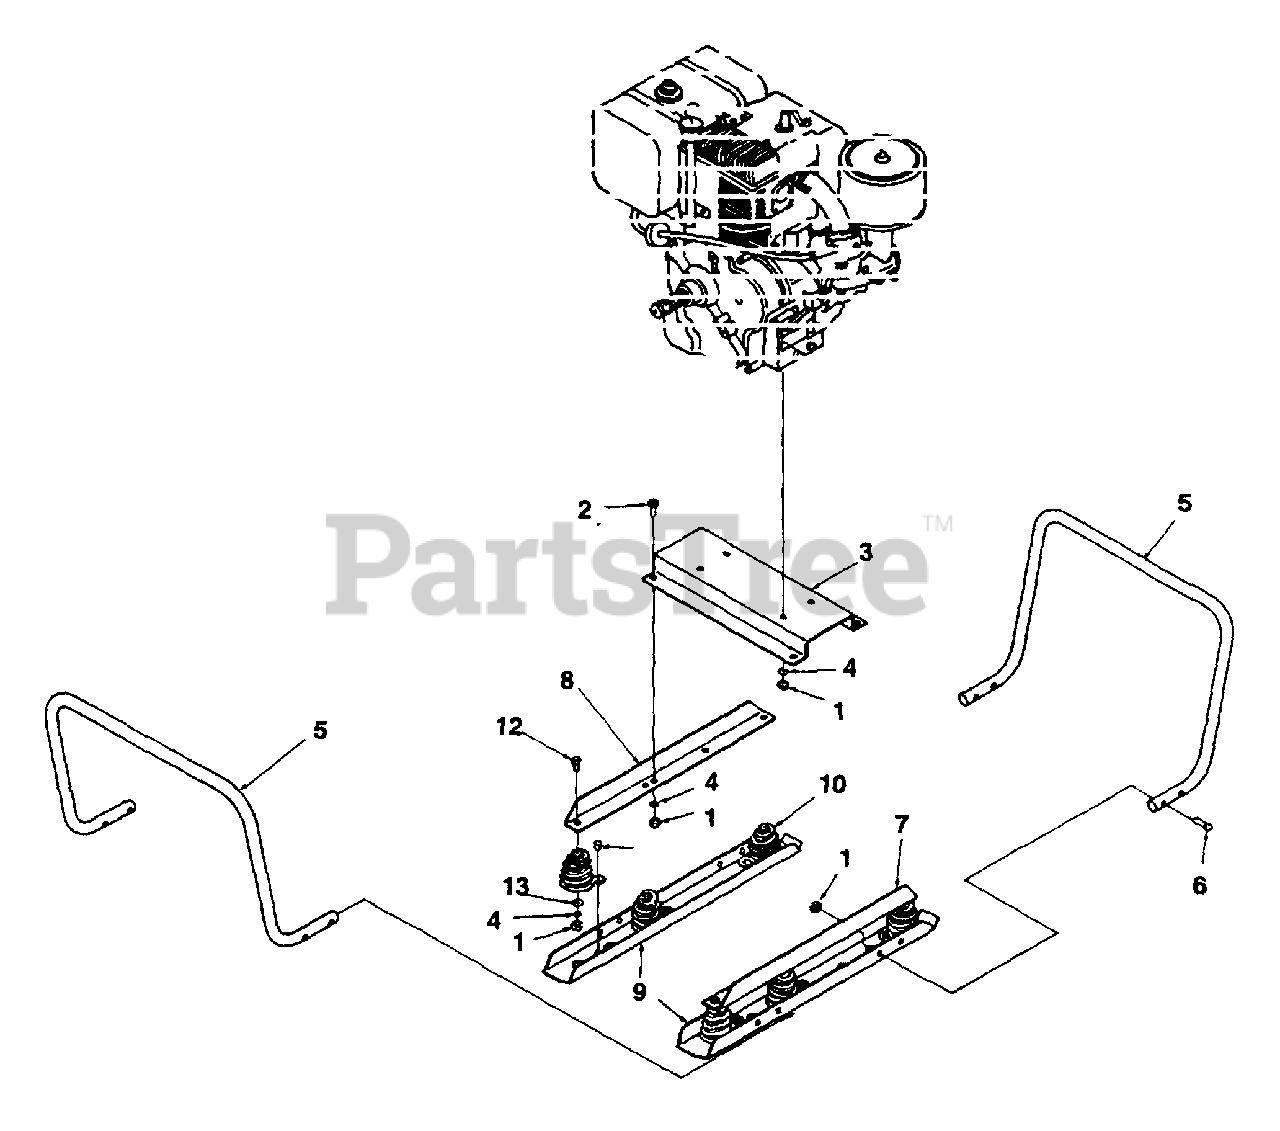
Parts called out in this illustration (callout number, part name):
1	NUT - Hex (5/16-18)
2	SCREW - Mach Hex Hd. (5/16-18 x 3/4)
3	BRACKET - Pump Engine
4	WASHER - Lock (5/16)
6	SCREW - Hex Hd. (5/16-18 x 1 1/2")
7	ANGLE - Base (left)
8	ANGLE - Base (right)
10	FOOT - Spring
12	SCREW - Cap Hex Hd. (5/16-18 x 1)
13	WASHER - Flat (5/16)
